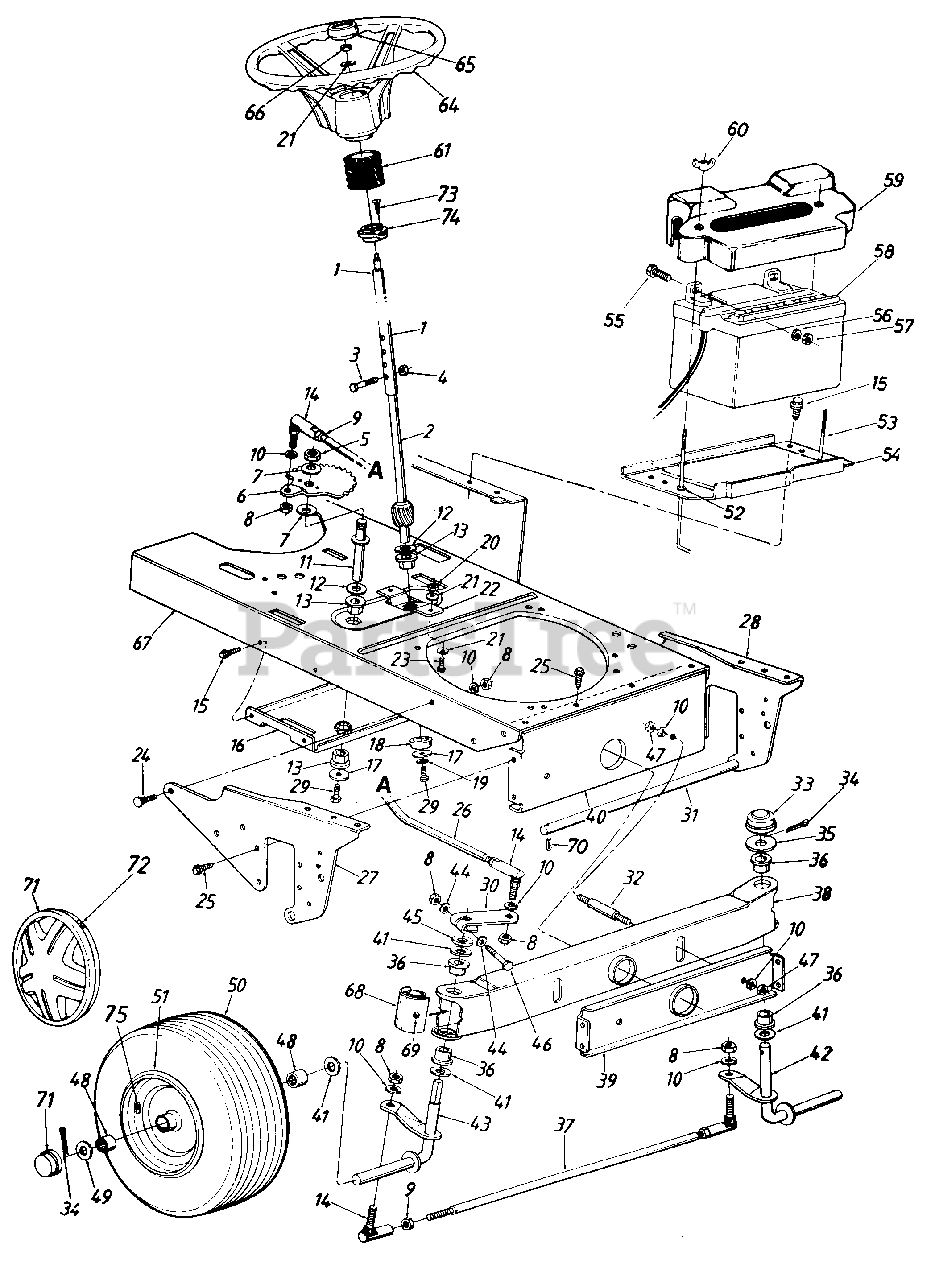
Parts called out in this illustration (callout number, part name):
1	Steering Column Ass'y.
2	Lower Steering Shaft
3	Hex Bolt 1/4-20 x 1.31" Lg.
4	Hex L-Nut 1/4-20 Thd.
5	Hex Nut 5/8-18 Thd.*
6	Steering Gear Segment
7	Bell-Wash. 5/8" I.D. x 1.25" O.D.
8	Hex Nut 3/8-24 Thd.
9	Hex Jam Nut 3/8-24 Thd.
10	L-Wash. 3/8" I.D.*
11	Steering Gear Segment Shaft
12	Fl-Wash. .64" I.D. x 1.24" O.D.
13	Hex Flange Brg. .63" I.D.
14	Ball Joint Ass'y.
15	Hex Wash. Hd. TT-Tap Scr. 1/4-20 x .5" Lg.
16	Deck Idler Support Brkt.
17	Fl-Wash. .33" I.D. x 1.25" O.D.
18	Spacer .985" I.D. x 1.25" O.D.
19	L-Wash. 5/16" I.D.*
20	Hex Nut 5/16-24 Thd.*
21	Bell-Wash. .345" I.D. x .88" O.D.
24	Ribbed Neck Bolt 3/8-24 x .8" Lg.
25	Hex Wash. TT-Tap Scr. 5/16-18 x .62" Lg.
26	Steering Drag Link
27	Pivot Bar Side Plate-R.H.
28	Pivot Bar Side Plate-L.H.
29	Hex Bolt 5/16-18 x .62" Lg.
30	Steering Arm
31	Deck Connecting Rod
32	Pivot Bar Shld. Bolt 3/8-16 x 5/8" Lg.
33	Cap
34	Cotter Pin 5/32" Dia.
35	Flat Washer
36	Flange Brg. .757" I.D.
37	Tie Rod 20.25" Lg.
38	Pivot Bar Assy.
41	Fl-Wash. .76" I.D. x 1.49" O.D.
42	Front Axle Ass'y.-L.H.
43	Front Axle Ass'y.-R.H.
44	Bowed Washer
45	Spacer .755n I.D. x 1.25" O.D.
46	Hex Bolt 3/8-24 x 2.25" Lg.
47	Hex Nut 3/8-16 Thd.
48	Needle Brg. .75" I.D.
49	Fl-Wash. .71" I.D. x 1.5" O.D.
51	Rim Only
52	Push Nut
53	Battery Hold Down Rod
54	Battery Carrier
55	Hex Bolt 1/4-20 x .62" Lg.*
56	L-Wash. 1/4" I.D.
57	Hex Nut 1/4-20 Thd.
58	Battery
59	Battery Cover
60	Wing Nut Plastic 1/4-20 Thd.
61	Steering Bellow
64	Steering Wheel
65	Steering Wheel Cap
66	Hex L-Nut 5/16-24 Thd.
67	Lower Frame
68	Pivot Bar End Cap
69	Grease Fitting
70	Internal Cotter Pin
71	Hub Cap
72	Spring Clip
73	Oval Hd. Cr.-Sunk Scr. #10 x 5/8" Lg.
74	Fl-Bearing .89" I.D. x 1.36" O.D.
75	Air Valve
